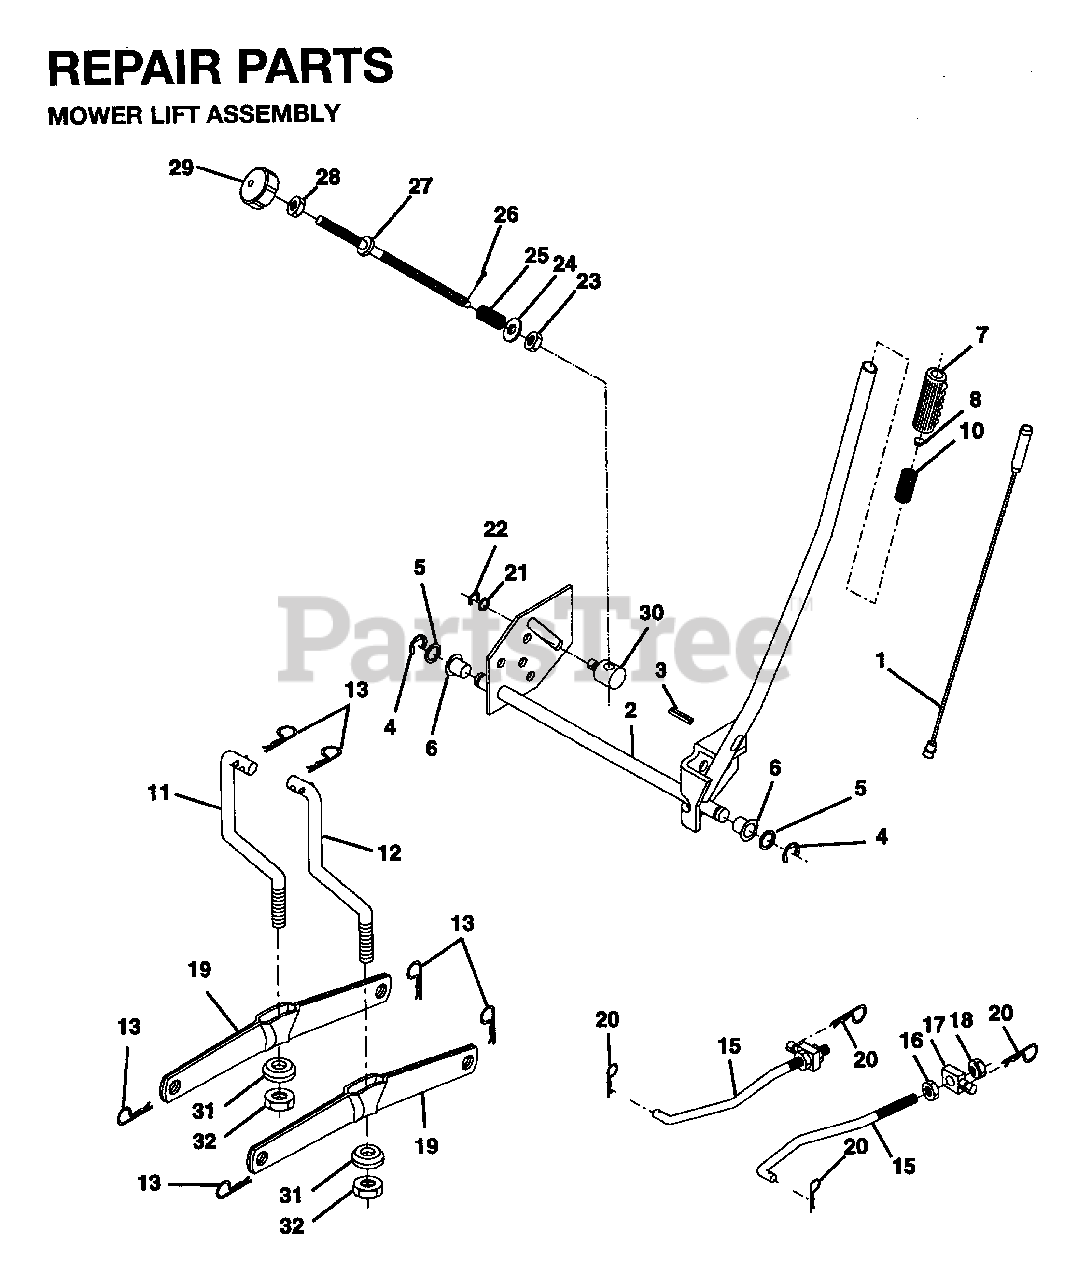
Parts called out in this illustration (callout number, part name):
1	WIRE ASM INNER
2	SHAFT ASM LIFT RH
3	PIN GROOVE
4	RETAINING RING LT
6	BEARING.NYLON
7	GRIP HANDLE
8	PLUNGER BUTTON KIT
10	SPRING, COMP T
11	LINK LIFT LH
12	LINK LIFT RH
13	RETAINER SPRING
15	FRONT LINK
16	NUT 1/2 X 13
17	TRUNION
18	NUT
19	ARM.REAR.SUSPENSION
20	SPRING RETAINER
22	KLIP RING
26	COTTER PIN
28	NUT
29	KNOB INF 3/8-16
30	TRUNION LT
31	BEARING PIVOT
32	NUT
